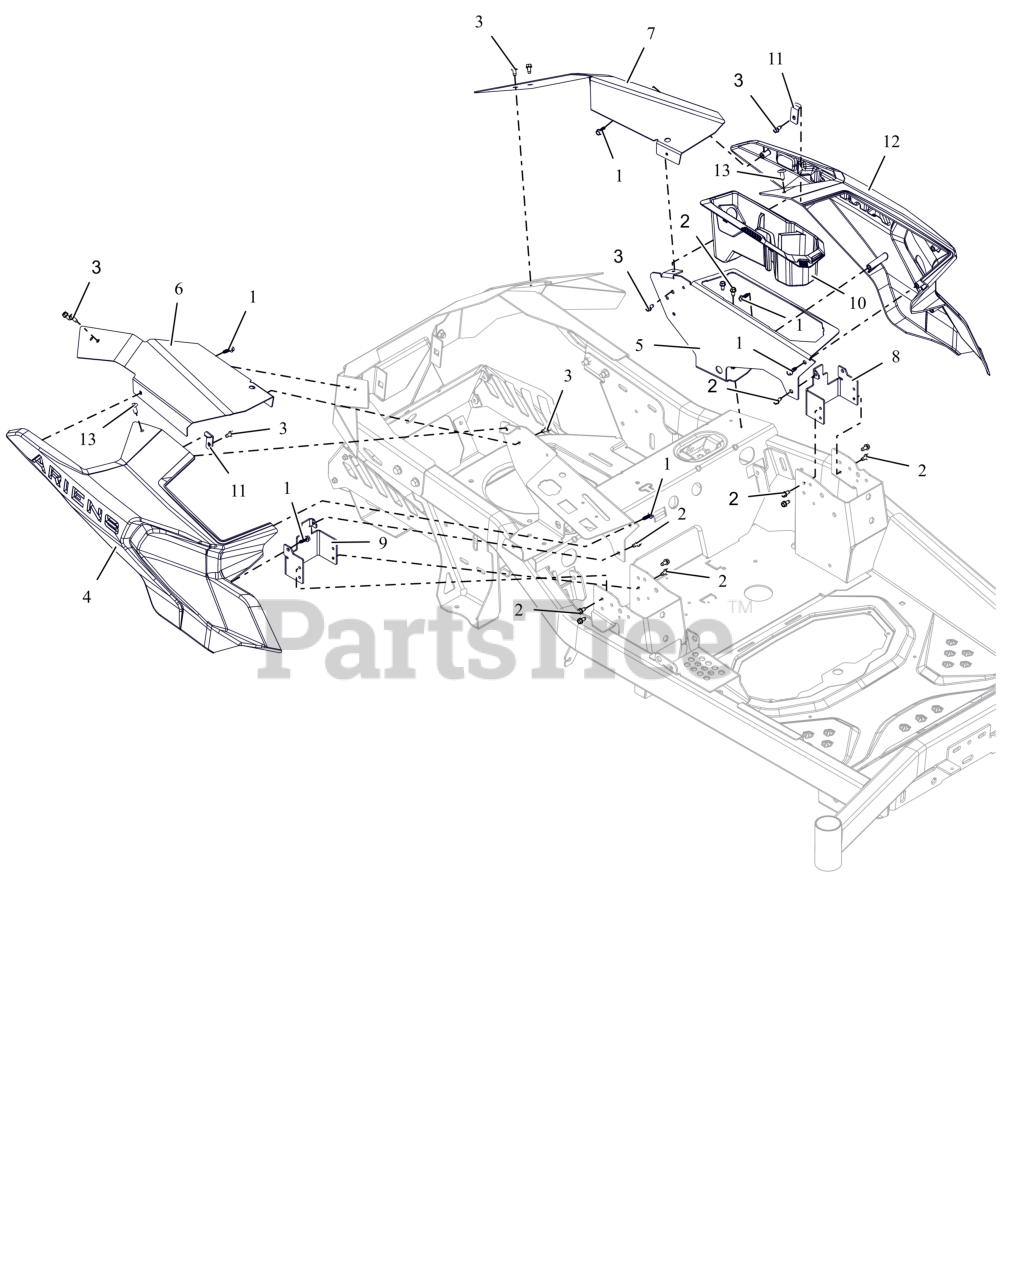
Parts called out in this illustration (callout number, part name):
1	SCR, PLASTITE .25-10X.75 ZCC
2	SCR-TAP .25-20X.50 HWH ZCC
3	SCR-TAP .25X.50 HWH ZB500
4	FENDER-RH-ARIENS
5	PANEL- CONTROL-LH-ARIENS
6	BRKT- REAR FENDER MOUNT-A-RH
7	BRKT-REAR FENDER MOUNT-A-LH
8	BRKT-FRONT FENDER MOUNT-A-RH
9	BRKT-FRONT FENDER MOUNT-A-LH
10	HOLDER- CUP - IKON
11	PLATE, FENDER HOLDDOWN (ORANGE)
12	KIT,LH ARIENS FENDER W/ DECAL
13	XMAS TREE FASTNER-BLACK
